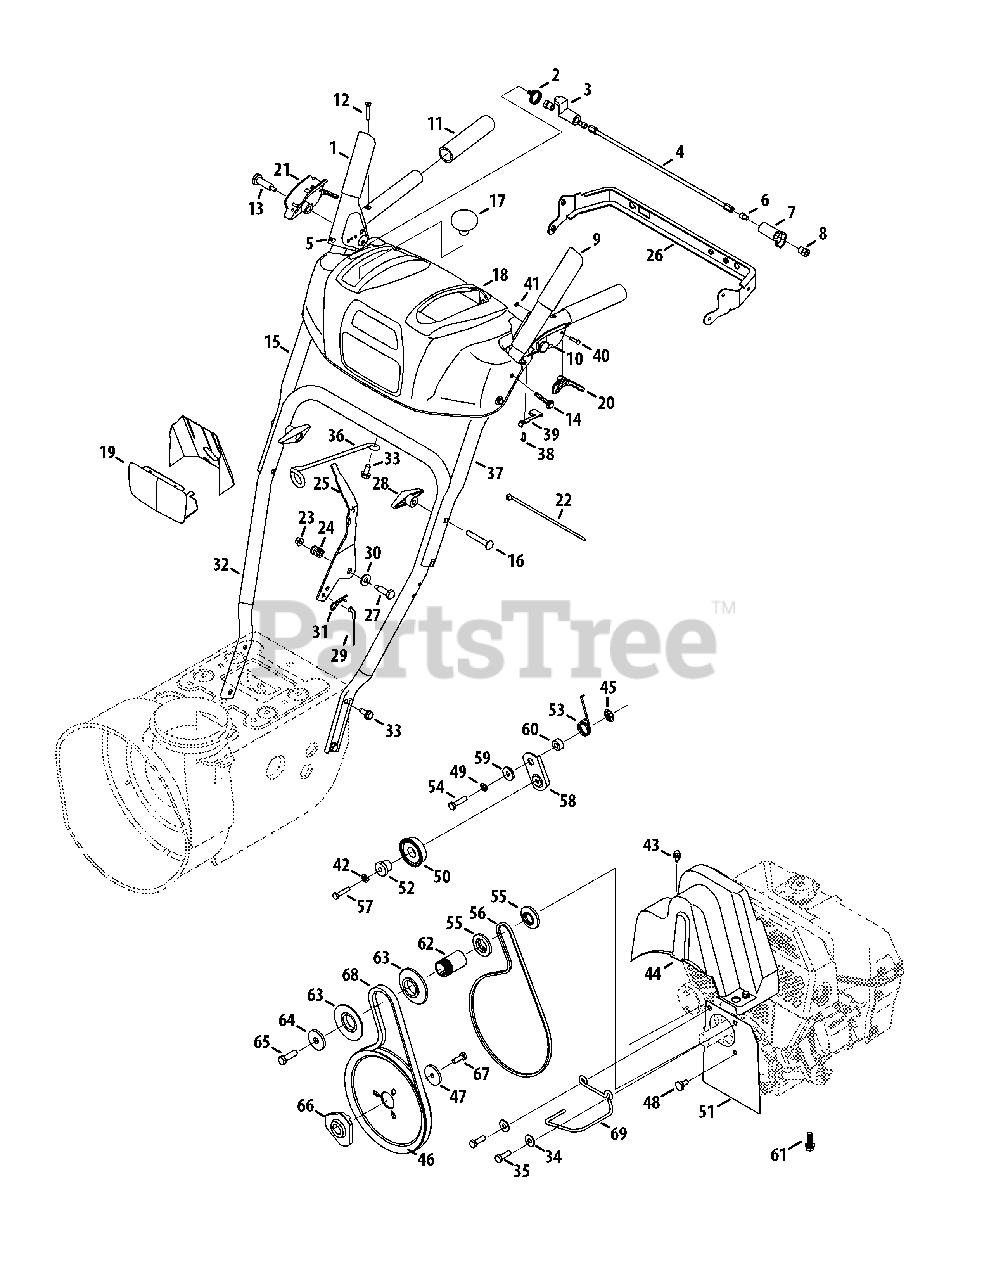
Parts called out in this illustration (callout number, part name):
1	Handle Engagement Ass’y RH
2	Torsion Spring
3	Lock Plate
4	Pivot Rod
5	Rubber Bumper
6	Screw, 1/4-20 x .500
7	Clutch Lock Cam
8	Shoulder Nut, 1/4-20
9	Handle Engagement Assembly LH
10	Handle Clutch Lock LH Assembly
11	Handle Grip
12	Screw, #10-24 x 0.375
13	Shoulder Screw, 1/4-20
14	Screw, 1/4-20 x 1.625
15	Upper Handle RH
16	Carriage Screw, 5/16-18 x 2.25
17	Shift Knob
18	Handle Panel
20	Steering Control
21	Handle Clutch Lock RH Assembly
22	Cable Tie
23	Flange Lock Nut, 1/4-20
24	Compression Spring
25	Shift Lever
26	Panel Bracket
27	Shoulder Screw
28	Wing Knob
29	Speed Selector Cable
30	Flat Washer
31	Click Pin
32	Lower Handle
33	Screw, 5/16-18 x 0.75
34	Flat Washer, .349 x .879 x .063
35	Screw, 5/16-24 x 1.00
36	Cable Guide
37	Upper Handle LH
38	Screw, #8-16 x 0.50
39	Clutch Lock Spring
40	Pin, 3/16
41	Retainer Ring
42	Lock Washer
43	AB Screw, 1/4-20 x 0.625
44	Belt Cover
45	Push-on Nut
46	Auger Pulley
47	Flat Washer
48	Shoulder Screw
49	Lock Washer
50	Idler Pulley Assembly
51	Plt., Cvr.
52	Spacer
53	Torsion Spring
54	Hex Screw, 5/16-24 x 1.25
55	Pulley Half
56	Belt, Wheel Drive
57	TT Screw, 1/4-20 x 1.25
58	Drive Clutch Idler Bracket
59	Shoulder Spacer
61	TT Sems Screw, 3/8-16 x 1.0
62	Spacer
63	Pulley Half
64	Flat Washer
65	Hex Bolt, 3/8-24 x 1.25
66	Pulley Adapter
67	Hex Bolt, 5/16-24 x 0.875
68	V-Belt,.500 x 35.00 Lg
69	Belt Guide
